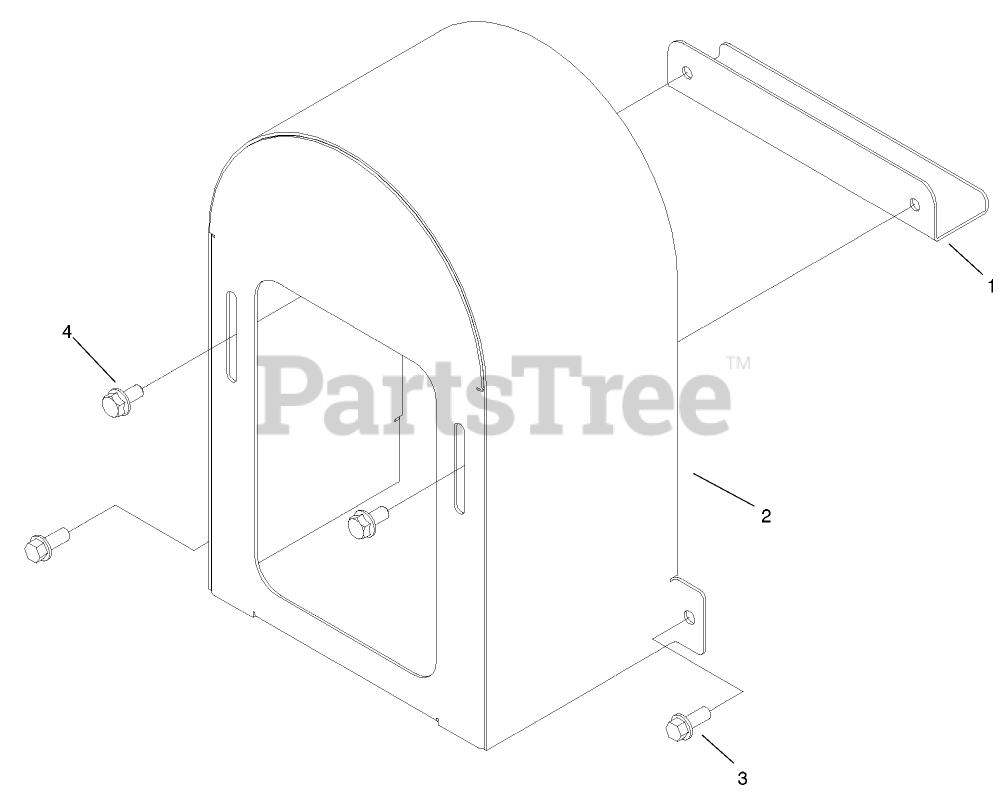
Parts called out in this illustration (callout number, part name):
1	BRACE ASM
2	COVER ASM
3	SCREW-HWHTF
4	SCREW-HHF
